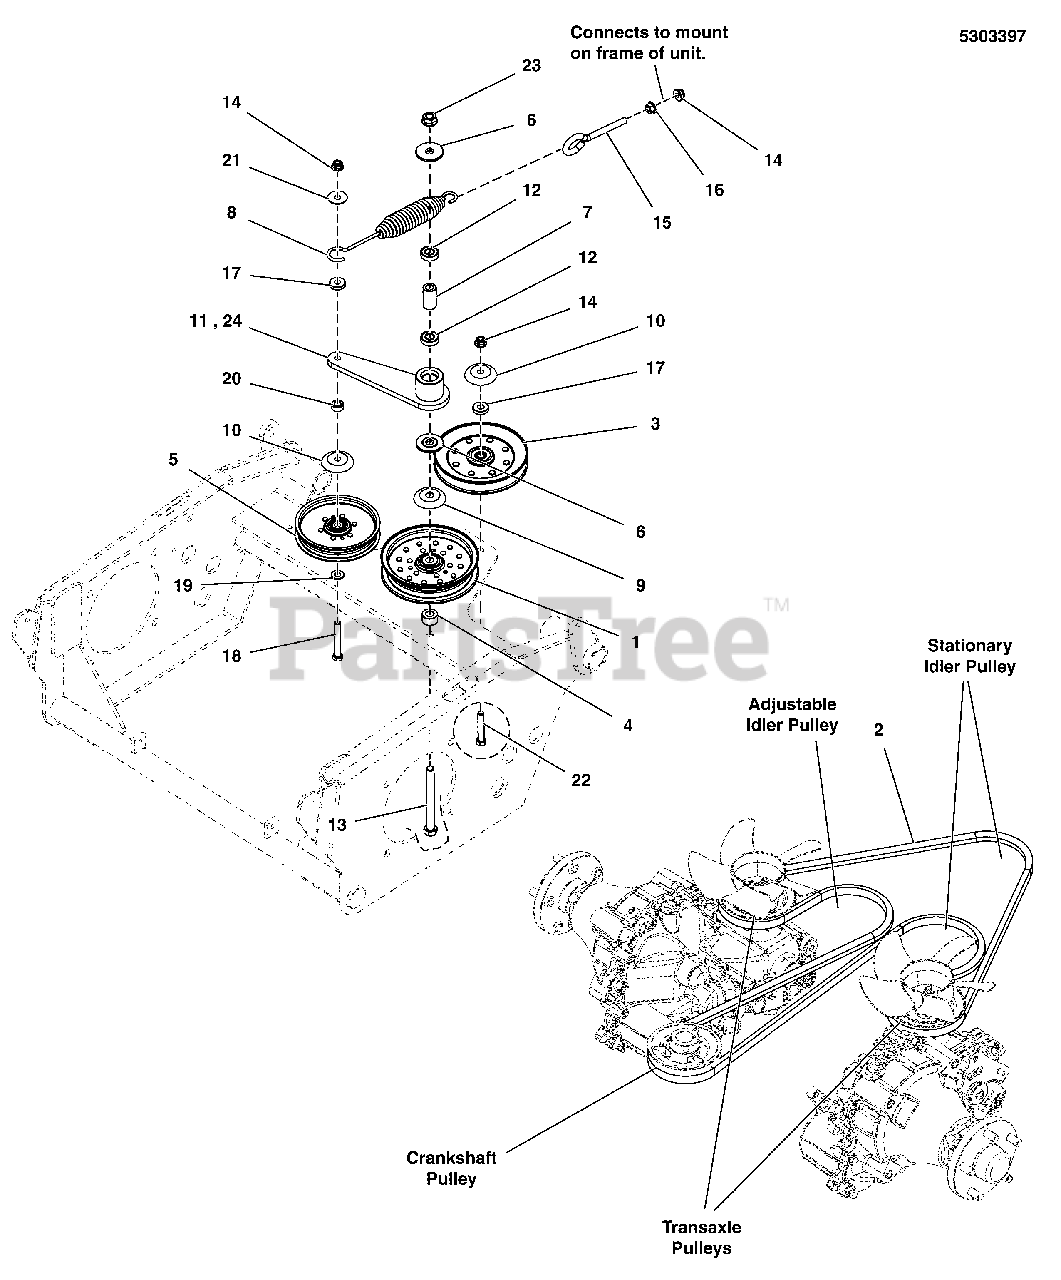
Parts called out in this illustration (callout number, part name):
1	PULLEY, IDLER, 5" OD, 1"FACE, 5.75 FL
2	BELT, B-SEC, 123"EL, ARAMID, WRPD
3	PULLEY-IDLER-V, 5.83OB, .38ID, .94W, STL
4	SPACER, .52 X 1.00 X .56, CZ
5	PULLEY, C-SEC, V-IDLER, 6.25"ODX3/8ID
6	SPACER, IDLER ARM, 1/2, PM
7	SPACER, .52 X .84 X 1.53, PM
8	SPRING-EXT, 1.25OD X 9.3LG X .142WR, BLK
9	SHIELD, PULLEY BEARING, CZ
10	SHIELD, BEARING PULLEY, 3/8ID, CZ
12	BEARING, BALL, AXLE
13	BOLT-1/2-13 X 5 GD5 YZ
14	NUT, 3/8-16 HEX NYLOCK FLANGE
15	EYE BOLT, 3/8-16 X 5, 2.88THRD (5021812)
16	NUT, 3/8-16 HEX SERRATED FLANGE
17	SPACER, .39 X 1.00 X .25
18	BOLT, 3/8-16 X 2-3/4 GD5 YZ
19	WASHER, 3/8 GD.9 FLAT
20	SPACER, .39 X 1.00 X .50, CZ
21	WASHER-3/8 FENDER
22	BOLT, 3/8-16 X 2-1/4 GD5 YZ
23	NUT, 1/2-13 HEX NYLOCK FLANGE
24	WELD, IDLER ARM, PUMP DRIVE, 6.38 - BLK
